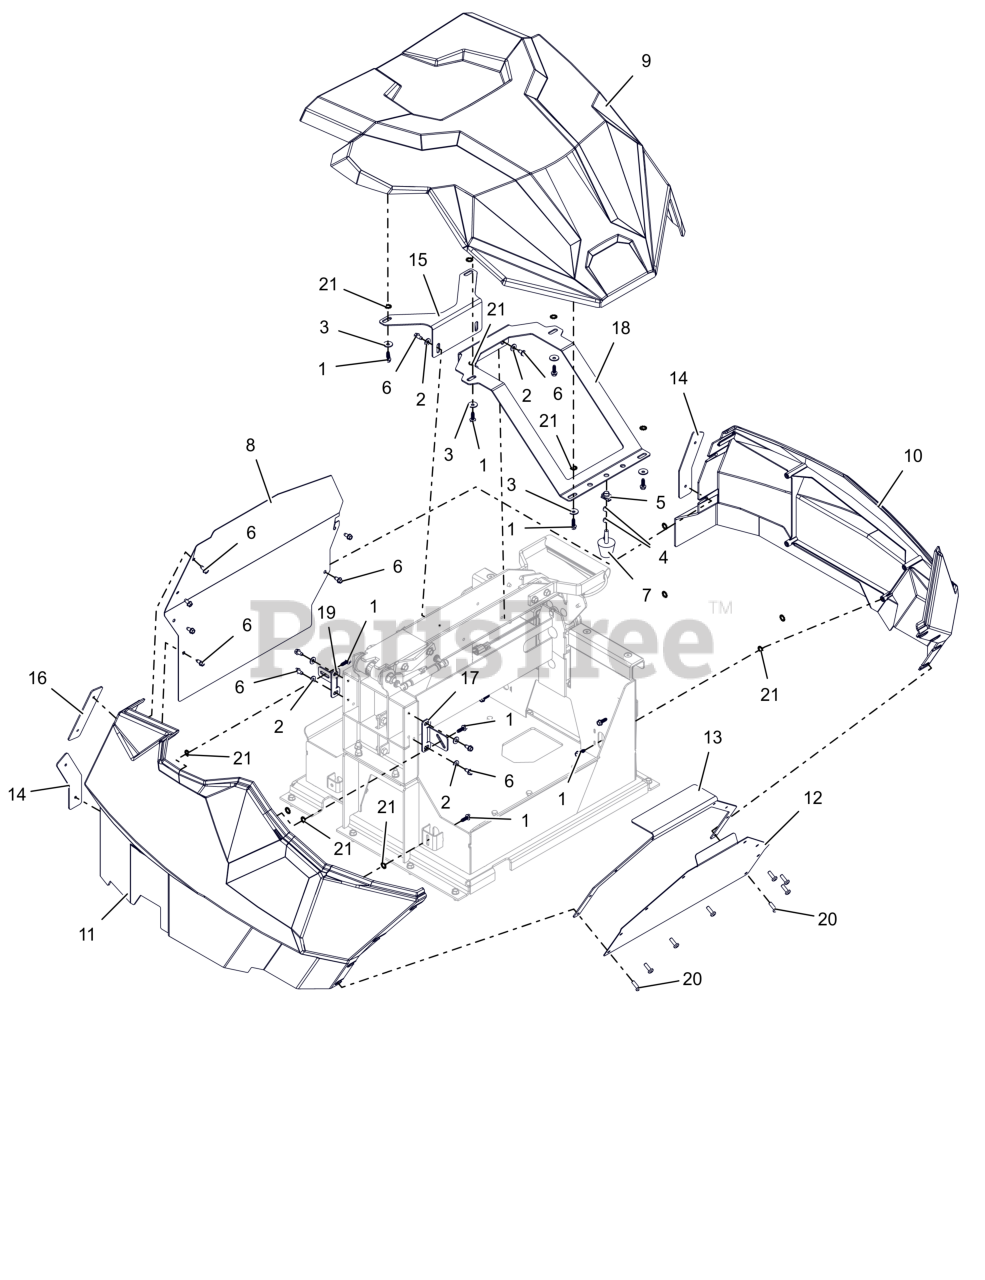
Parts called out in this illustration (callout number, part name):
1	SCR, PLASTITE-HWH 0.25 X 0.75 ZC120
2	WSHR,FLT .281X.625X.065 ZCC
3	WSHR, BLVL - .250 X .815 X .061 ZFS
4	NUT-JAM .312-18 G2 ZCC
5	NUT-CLIP RETAINER 5/16-18X.56
6	SCR-TAP .25-20X.50 HWH ZCC
7	BUMPER,STUD MOUNTED CONE SHAPE
8	BRKT, FENDER - REAR (BLACK)
9	HOOD, BATTERY CAPTURE
10	FENDER, BATTERY CAPTURE - LH
11	FENDER, BATTERY CAPTURE - RH
12	BRKT, FENDER - FRONT (RED)
13	PLATE, BACK - FRONT (BLACK)
14	PLATE, BACK REAR LH (BLACK)
15	SUPPORT, HOOD (BLACK)
16	PLATE, BACK - REAR UPPER (BLACK)
17	SUPPORT, FENDER (BLACK)
18	SUPPORT, HOOD (BLACK)
19	SUPPORT, FENDER (BLACK)
20	SCR-TAP 1/4-20X3/4 LPAN TL BZ
21	WSHR-LK-EXT 0.326X0.599X0.031 ZCC
